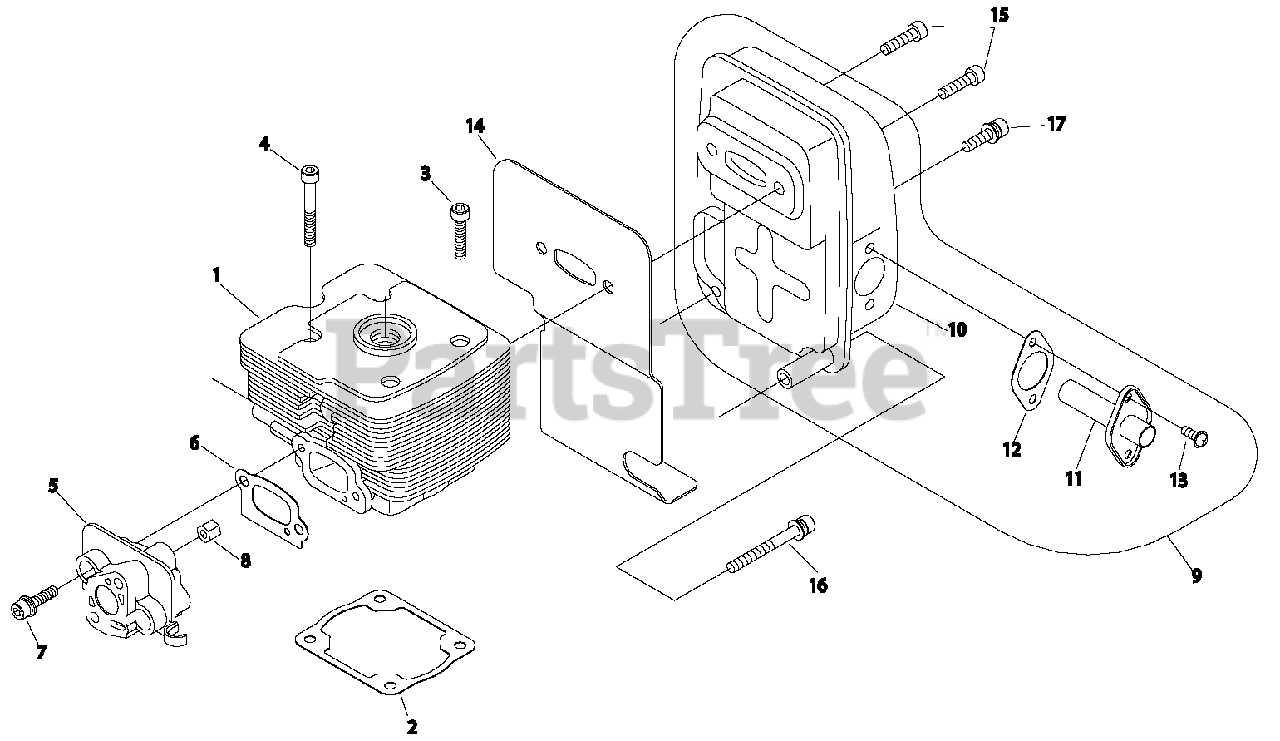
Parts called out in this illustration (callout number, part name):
1	CYLINDER
2	GASKET, CYLINDER
3	SCREW - 5X25
4	SCREW - 5X35
5	INSULATOR, INTAKE
6	GASKET, INTAKE
7	SCREW - 5X30
8	NUT
9	MUFFLER ASSY
10	MUFFLER
11	GUIDE, EXHAUST
12	SHIELD, EXHAUST
13	SCREW - 4X12
14	SHIELD, EXHAUST
15	SCREW - 6X25
16	SCREW - 5X45
17	SCREW - 5X16
